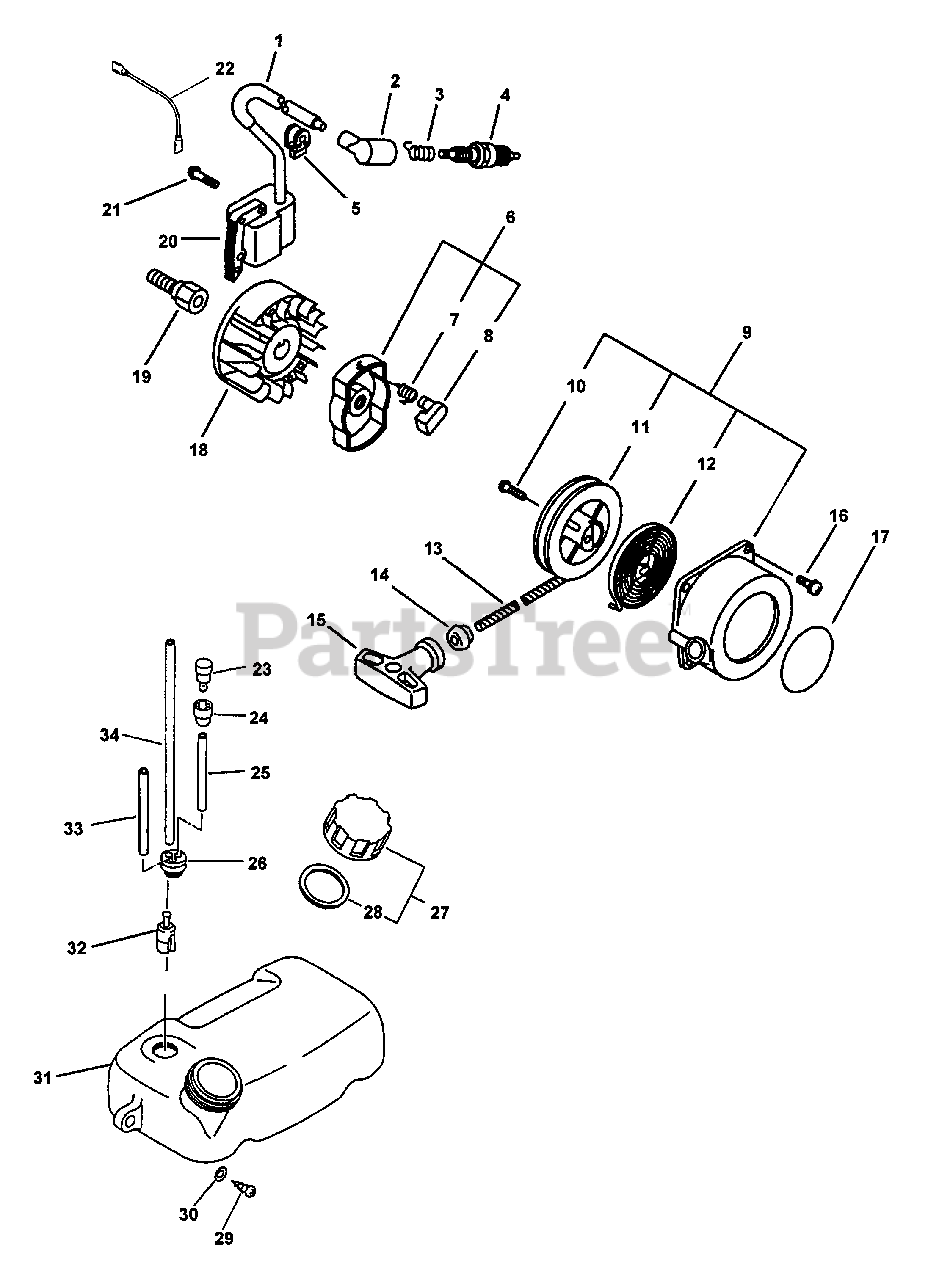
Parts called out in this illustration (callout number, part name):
2	CAP, SPARK PLUG
3	TERMINAL, SPARK PLUG CAP
4	SPARK PLUG -- BPM-7Y
6	STARTER PAWL ASSY
7	SPRING, RETURN
8	PAWL, STARTER - BLACK
9	STARTER ASSY
11	REEL, ROPE
12	SPRING, REWIND
13	RePower BULK ROPE - 200 FEET
14	GUIDE, ROPE
15	GRIP, STARTER
16	SCREW - 4X22
17	LABEL - ECHO
18	FLYWHEEL
19	HUB, FAN
20	COIL, IGNITION
21	SCREW - 4X22
22	LEAD - GROUND
23	VENT, FUEL TANK
24	COVER, VENT
25	PIPE - 3X5X90 -- BLACK
26	GROMMET
27	CAP ASSY
28	GASKET, CAP
29	SCREW - 5X20 -- TAPPING
30	WASHER - 5
31	TANK, FUEL
32	FILTER, FUEL
33	PIPE - 3X6X110 -- CLEAR
34	PIPE - 3X5X210 -- BLACK
